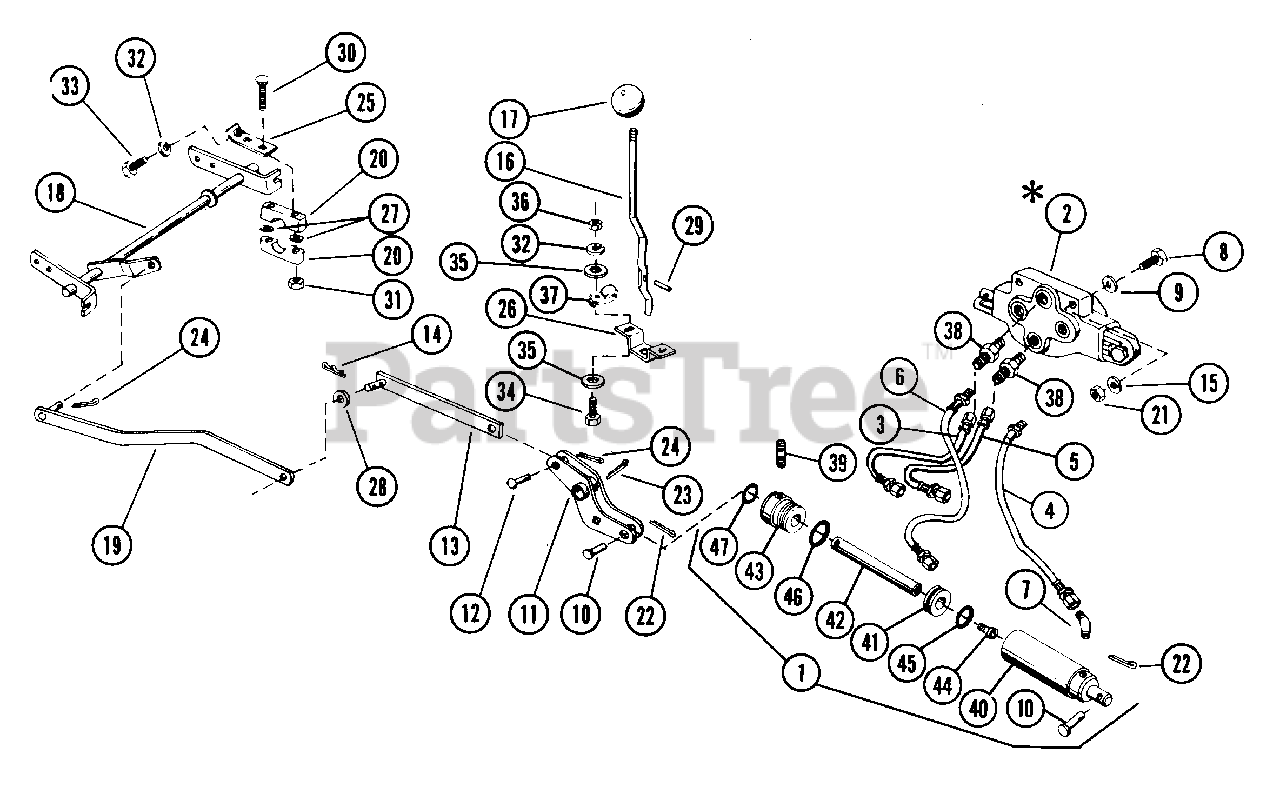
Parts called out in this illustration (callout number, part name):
1	CYLINDER ASSEMBLY
2	CONTROL VALVE
3	HYDRAULIC HOSE
4	HYDRAULIC HOSE
5	HYDRAULIC HOSE
6	HYDRAULIC HOSE
7	ADAPTER 45 9/16 TO 1/4
8	BLT-HEX .25-20X1.50 PL GR5
9	WSHR-FL-STL.281X.62X.065 PL
10	PIN-CLEV .494X1.94 YWZC
11	BELLCRANK
12	RVT-BTN .62X1.50 SPL
14	PIN-HAIR INT .09X.188 PL
15	WSHR-LK .250X.077 HVY PL
16	CONTROL ROD
17	KNOB-STEERING LOCK
18	FRONT ROCK SHAFT SERVICE ASSEM
19	FRONT ROCK SHAFT CONNECTOR LIN
21	NUT-HEX .250-20 PL
22	PIN-COTR .12X1.0 PL
23	PIN-COTR .18X1.25 PL
24	PIN-COTR .18X1.0 PL
26	BRACKET
27	WSHR-FL-STL .406X.750X.005
28	WSHR-FL-STL.812X1.500X.139
29	PIN-GRV .250X.75 TP B PL
30	BLT-RDHDSQNK .38-16X2.25 SHTPL
31	NUT-LK .375-16 PL
32	WSHR-LK .312X.097 PL HVY
33	BLT-HEX .31-18X1.25 PL GR5
34	BLT-HEX .31-18X.75 PL GR2
35	WSHR-FL-STL .38X.875X.083 PL
36	NUT-HEX .312-18
37	J-CLAMP
38	CONNECTOR
39	ADAPTER
40	CYLINDER BODY
42	PISTON ROD
43	PISTON ROD GUIDE
44	SCR-SKH .38-24X1.00
45	O-RING 1.625X2.000
46	O-RING 1.937X2.125
47	O-RING 1.000X1.250X
